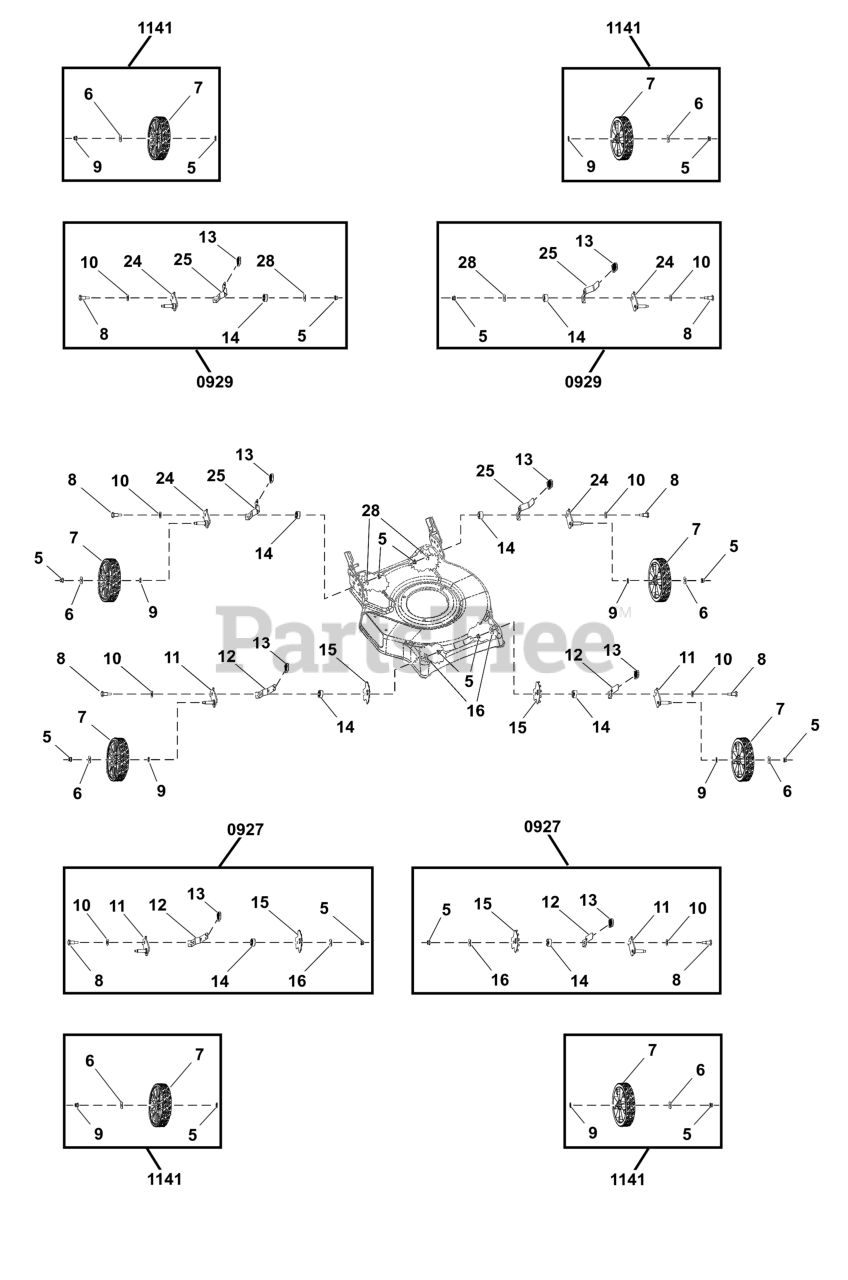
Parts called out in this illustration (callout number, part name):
5	NUT, Lock
6	WASHER, Flat
7	WHEEL
8	BOLT
9	WASHER, Flat
10	WASHER, Flat
11	ASSEMBLY, Axle, Front
12	LEVER, Height Adjust, Front
13	HANDLE, Height Adjust
14	SPACER, Height Adjust
15	BRACKET, Height Adjust
16	WASHER, Flat
24	ASSEMBLY, Axle, Rear
25	LEVER, Height Adjust, Rear
28	WASHER, Flat
0927	KIT, Front Axle
0929	KIT, Rear Axle
1141	KIT, Wheel
